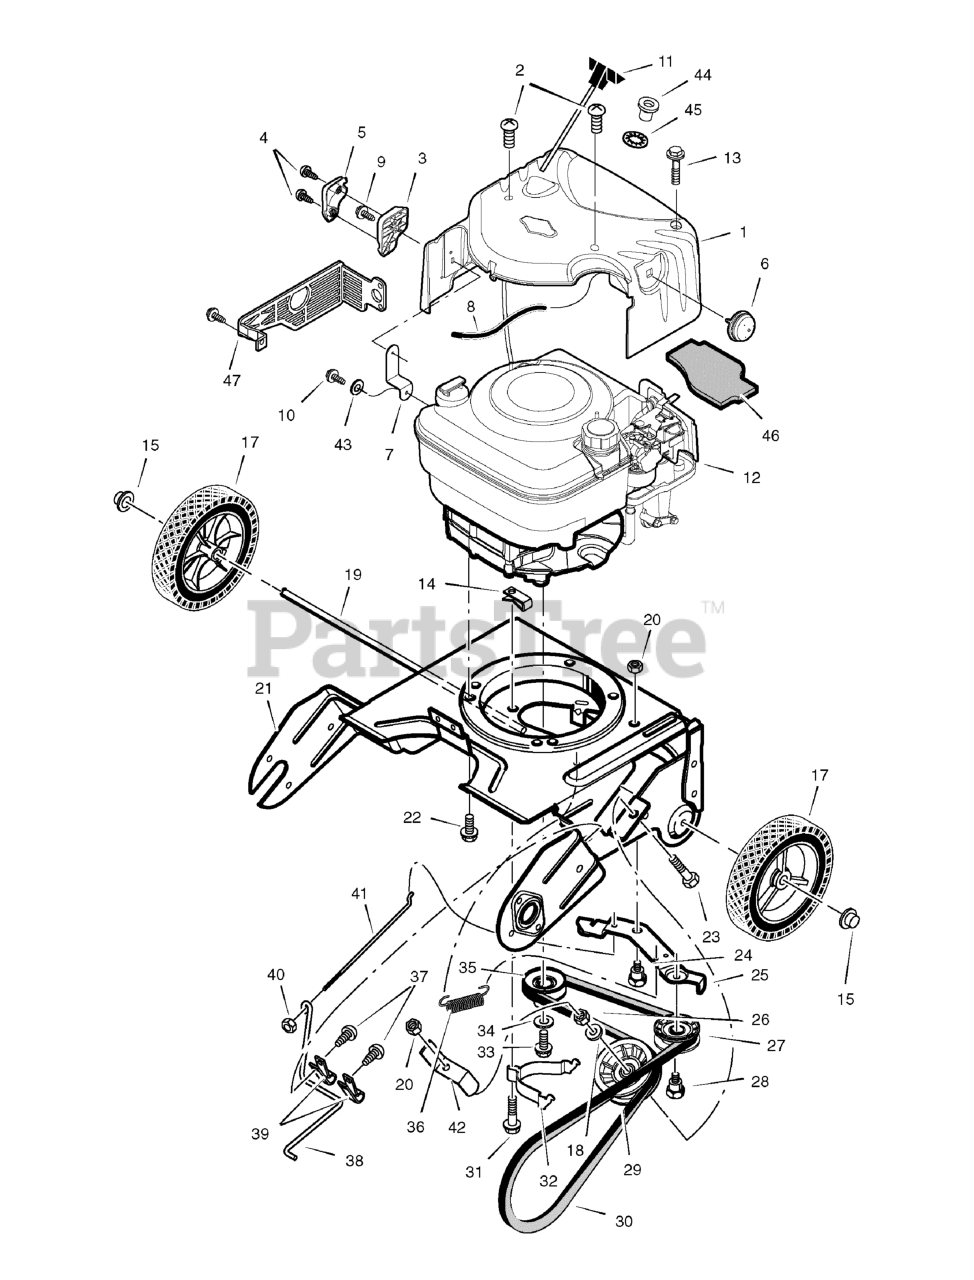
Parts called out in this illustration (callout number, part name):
1	Cover, Top
3	Base, Chute Rod
5	Cover, Chute Rod
6	Primerbulb, Red
7	Bracket, Engine Chute
11	Handle, Starter
12	Engine *
14	Retainer
15	Nut, Push Cap
17	Wheel & Tire
18	WASHER, Flat, 13/32
21	Frame, Motor Box
23	Bolt
24	Bolt, Shoulder
25	Bracket, Idler Arm
26	Nut
27	Pulley, V-Belt
28	Bolt, Shoulder
29	Pulley, Flat Idler
32	Guide, Belt
33	Screw
34	Washer
38	Arm, Brake
40	Nut
41	Rod, Adjustment
42	Guide, Belt
43	Lockwasher
44	Guide, Rope
45	Spring Grip Washer
46	Seal, Foam
47	Guard, Muffler
